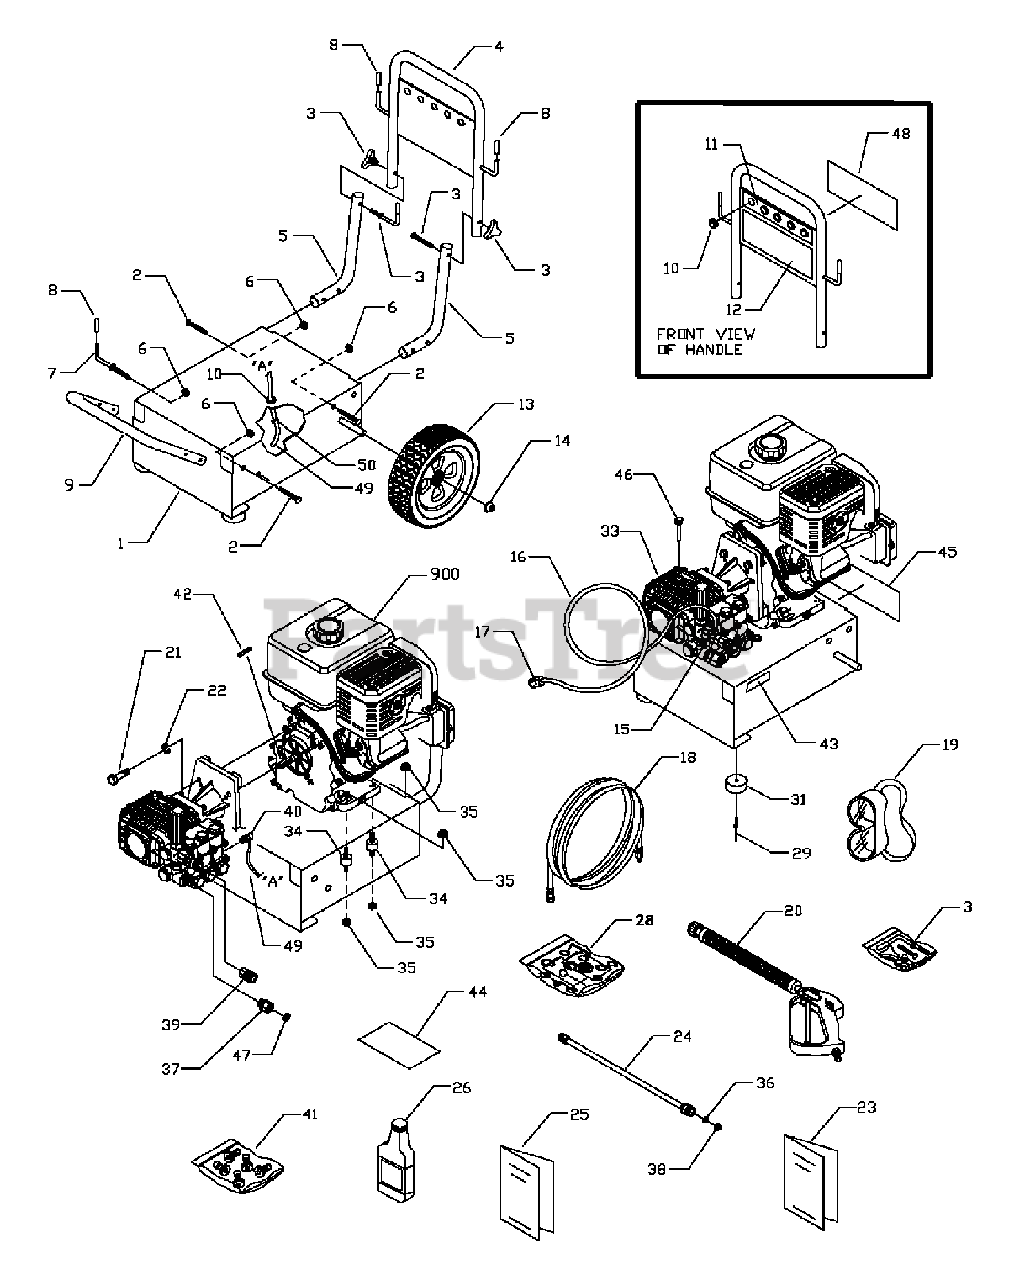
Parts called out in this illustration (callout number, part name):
2	BOLT, Carriage
3	KIT, Handle Hardware
4	HANDLE
5	SUPPORT, Handle
6	NUT, Hex Flange
7	HOOK, Square Neck Gun
8	CAP, Black Vinyl
10	GROMMET
11	DECAL, 5 QD Nozzles
12	DECAL, Unit
13	ASSEMBLY, Wheel
15	CLAMP, Hose
16	HOSE, Chemical Inject
17	FILTER, Chemical Hose
18	HOSE
19	GOGGLES, Safety
20	GUN, with Molded Grip
21	CAPSCREW, Socket Head
22	WASHER, Lock
23	MANUAL, Owners
24	ASSEMBLY, Wand Extension with QD
25	MANUAL, Engine
26	BOTTLE, Oil
28	KIT, O-Ring Maintenance
29	BLIND RIVET
31	VIBE MOUNT, with Washer
33	ASSEMBLY, Pump (see pages 18-19)
34	VIBRATION MOUNT, Double Ended
35	NUT, Flange
36	SCREEN, Gun Inlet
37	INLET, Garden Hose
38	O-RING, High Pressure Hose
39	QUICK CONNECT
40	VALVE, Thermal Relief
41	KIT, Nozzles QD
42	KEY
43	DECAL, Cool Down System
44	CARD, Owners Registration
45	DECAL, PW, Snapper
47	FILTER, Inlet
48	DECAL, Warning/Start
49	HOSE, Thermal Relief
50	CLAMP, Hose Band
0140	WASHER, 5/16
900	ENGINE, NSP
